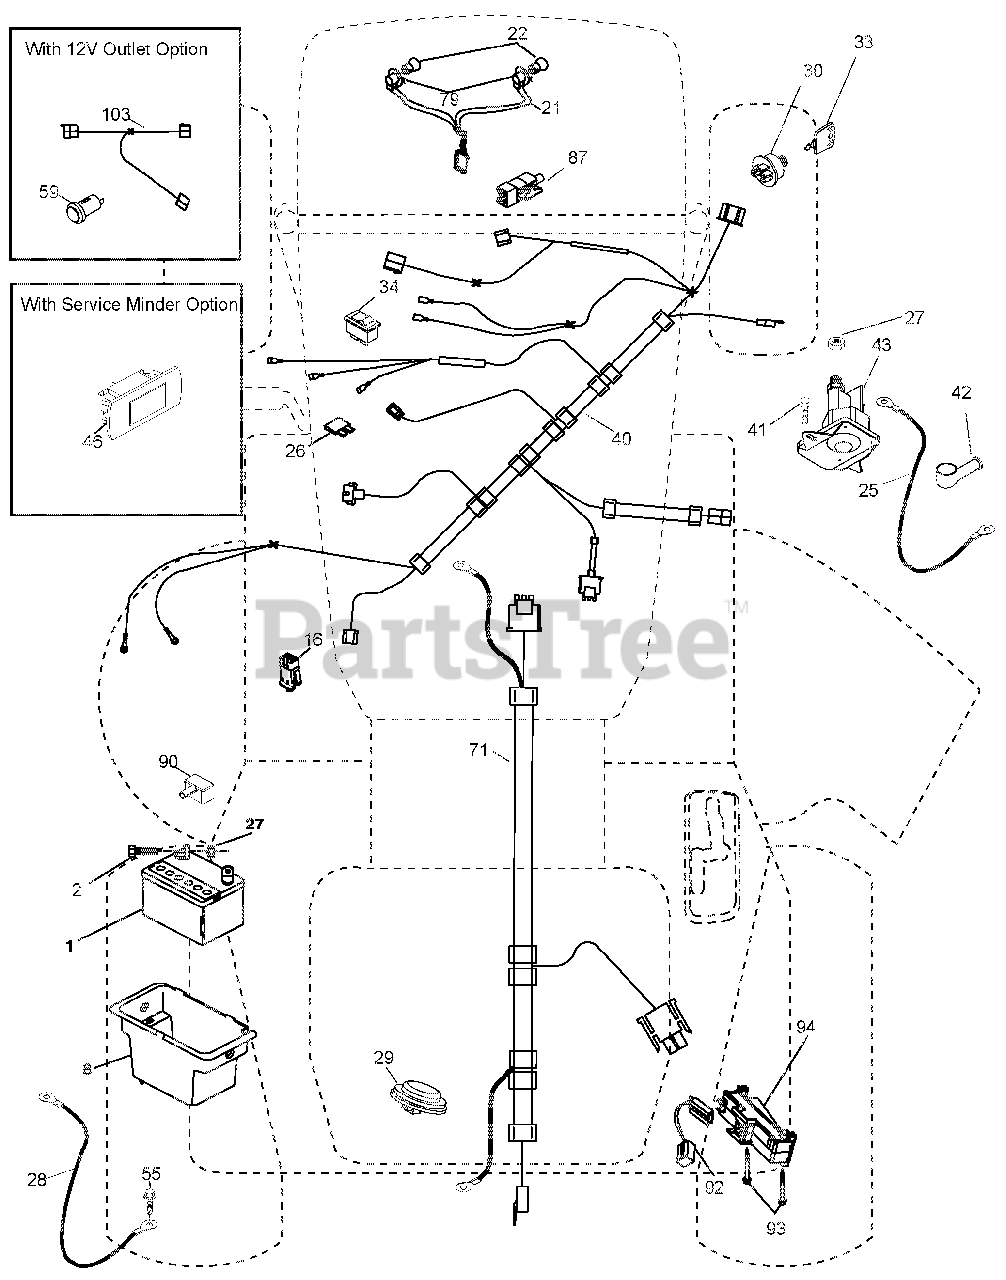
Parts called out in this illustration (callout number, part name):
1	BATTERY.12.VOLT.28.AMP.WET
2	BOLT.HEX.HD.1/4-20UNC X 3/4
8	BOX.BATTERY.MNT.REAR.LT.TEX.BL
16	SWITCH.INTERLOCK.NONO.GRAY
21	HARNESS ASM.LIGHT.22"(4152J)
22	BULB.LIGHT.#1156
25	CABLE.STARTER.6GA.BL/RED.14.5"
26	FUSE.20 AMP.
27	Nut, Keps Hex 1/4-20 unc
28	CABLE.BLACK.22"REAR BATT.TEX
29	SWITCH.SEAT.DELTA.OPC.9LB.
30	SWITCH.IGN.DLTA.P-IN.ROS
33	KEY/CHAIN.BLISTER PACK.GEN.CE
34	SWITCH.LIGHT/RESET.B/B/RED.
40	HARNESS.IGN.DASH.CBL.YTGT.PRED
41	Screw 1/4-20 x 1/2
42	COVER.TERMINAL.RED
43	SOLENOID.W/BRASS PLUNGER.2005
55	SCREW.5/16-18X3/4.SMGML.TAP/R
71	HARNESS.IGN.CHASS.TEX.REAR.BAT
79	SOCKET ASM.BULB.TWISTLOCK
87	SWITCH.INTRLCK.CLUTCH.CABLE.TX
90	COVER TERMINAL BATTERY FR. TEX
92	HARNESS.PIGTAIL.CONSLE.ROS.MLK
93	SCREW.PLASTITE.10-14 X 2.0
94	MODUAL REVERSE ROS
